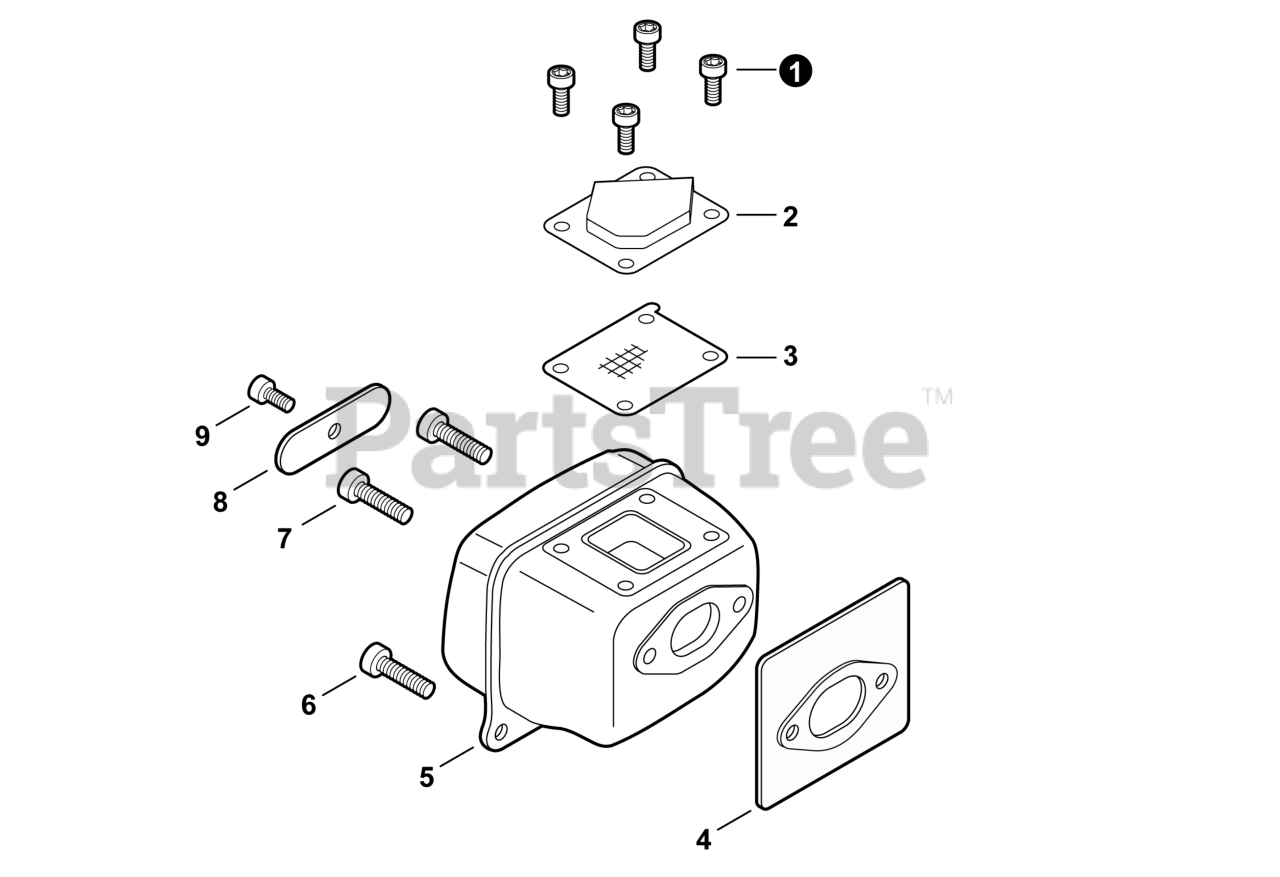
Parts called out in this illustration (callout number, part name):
1	BOLT, TORX 4x8
2	GUIDE, EXHAUST
3	SCREEN, SPARK ARRESTER
4	GASKET, EXHAUST
5	MUFFLER
6	BOLT, TORX 5x20
7	BOLT, TORX 5x20
8	PLATE, MUFFLER
9	BOLT, TORX 4x8
